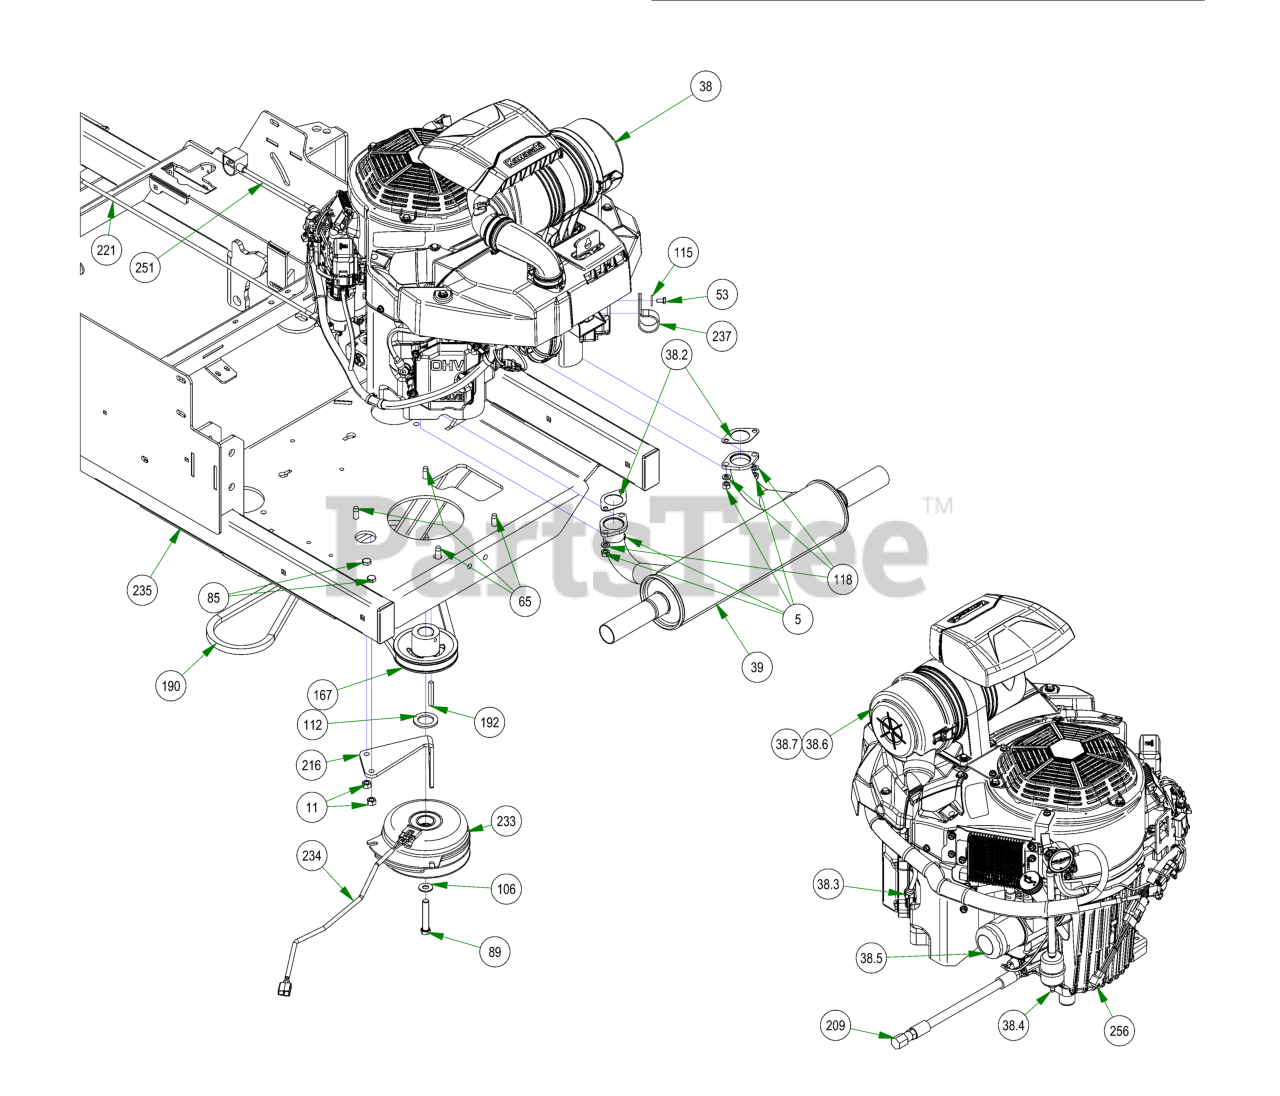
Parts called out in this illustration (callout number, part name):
5	M8-1.25 DIN 934 HEX NUT (CL.8) ZINC
11	3/8-16 HEX NUT ZINC
32	1 1/2 x 3 Frame Plug
38	Kawasaki FX1000 Engine
38.2	Exhaust Gasket
38.3	Spark Plug - Kawasaki
38.4	Universal Inline Fuel Filter
38.5	Oil Filter
38.6	Canister Air Filter- Outer
38.7	Canister Air Filter- Inner
39	2019 Rebel/Rogue Kawasaki 1000 Muffler
53	M6-1.0 X 12MM DIN 933 HEX TAP BOLT (CL 8.8) ZINC
65	3/8-16 X 1-1/8HEX WASHER UNSLOT SERRATED
85	3/8-16 X 1-1/4 HEX CAP SCREW (GR.5) ZINC
89	7/16-20 X 2-1/2 HEX Bolt GR 8 W/ Patch
106	3/8 FLAT WASHER USS (1" OD) ZINC
112	1.140 ID X 1.750 OD X .132 THICK FLAT WASHER PLAIN
115	1/4 USS FLAT WASHER (3/4 OD) ZINC
118	5/16 SPLIT LOCKWASHER ZINC
167	4 3/4 Motor Pulley
190	2019 Rogue Pump Belt 68"
192	1/4 X 2 SQ MACHINERY KEY 1018 STL PLAIN
209	Kawasaki Oil Drain
216	PTO Engager Holder
221	24" Red Battery Cable
233	Clutch Assembly
234	Clutch Pigtail
235	2023 Rogue Frame - Painted
237	Diesel Hydraulic Hose Clamp
251	Starter Cable
256	Harness Adaptor for Kawasaki EFI
